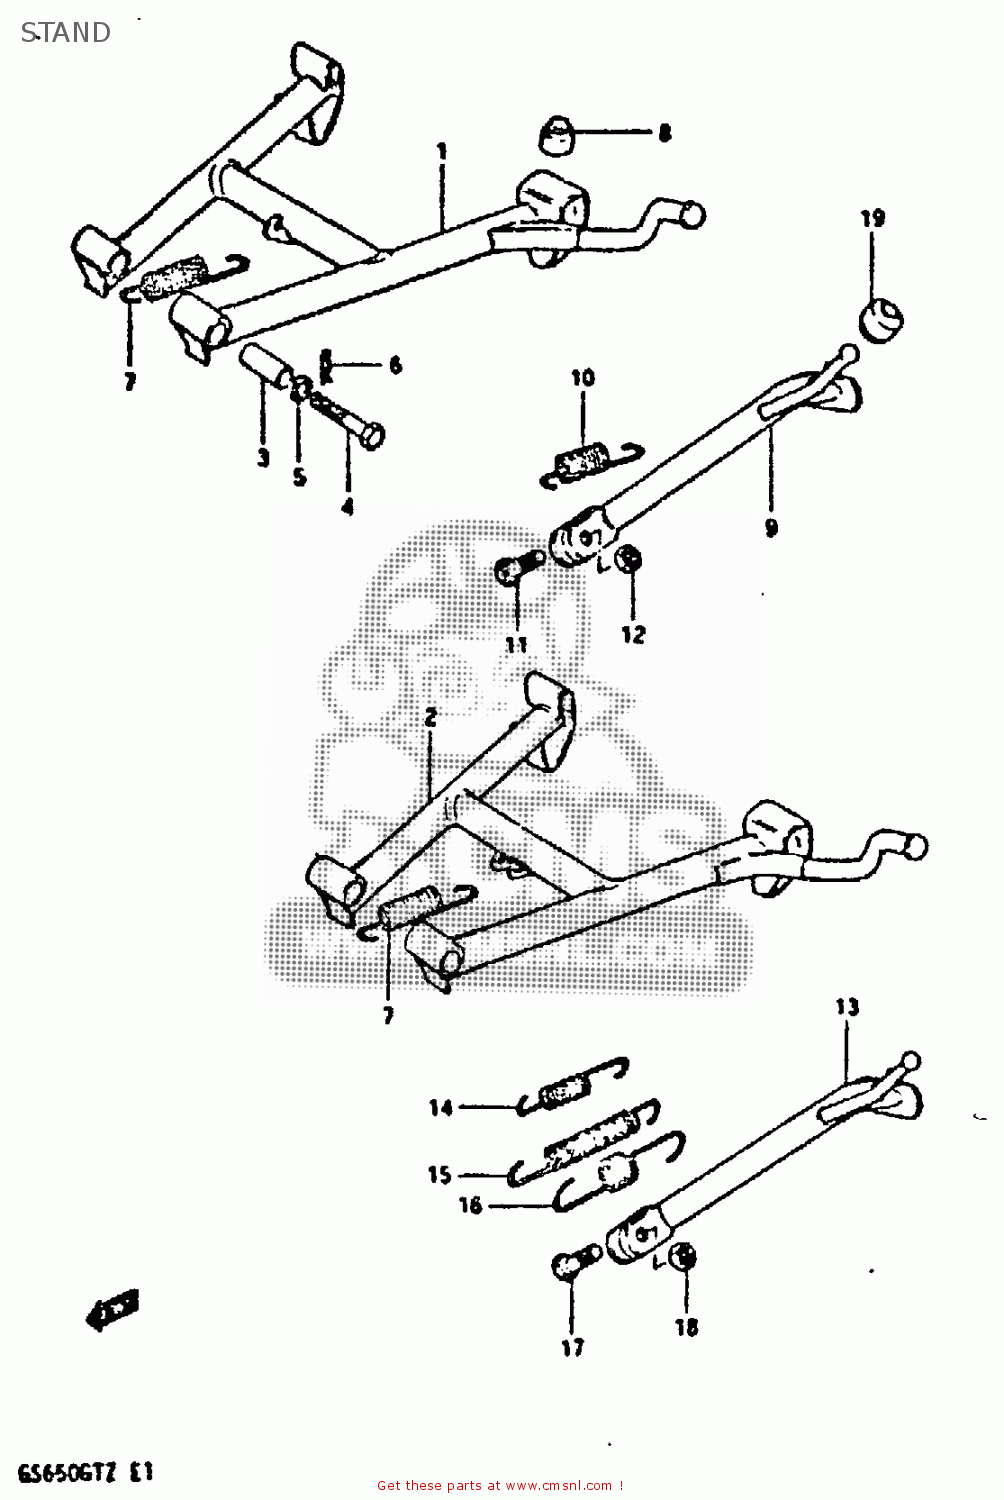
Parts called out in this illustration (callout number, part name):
1	STAND,CENTER
3	SPACER(10X16X38.8)
4	BOLT
5	LOCK WASHER
6	CLIP
7	SPRING
8	CUSHION
9	STAND,SIDE
10	SPRING
11	BOLT(10X30)
12	NUT
19	CUSHION
